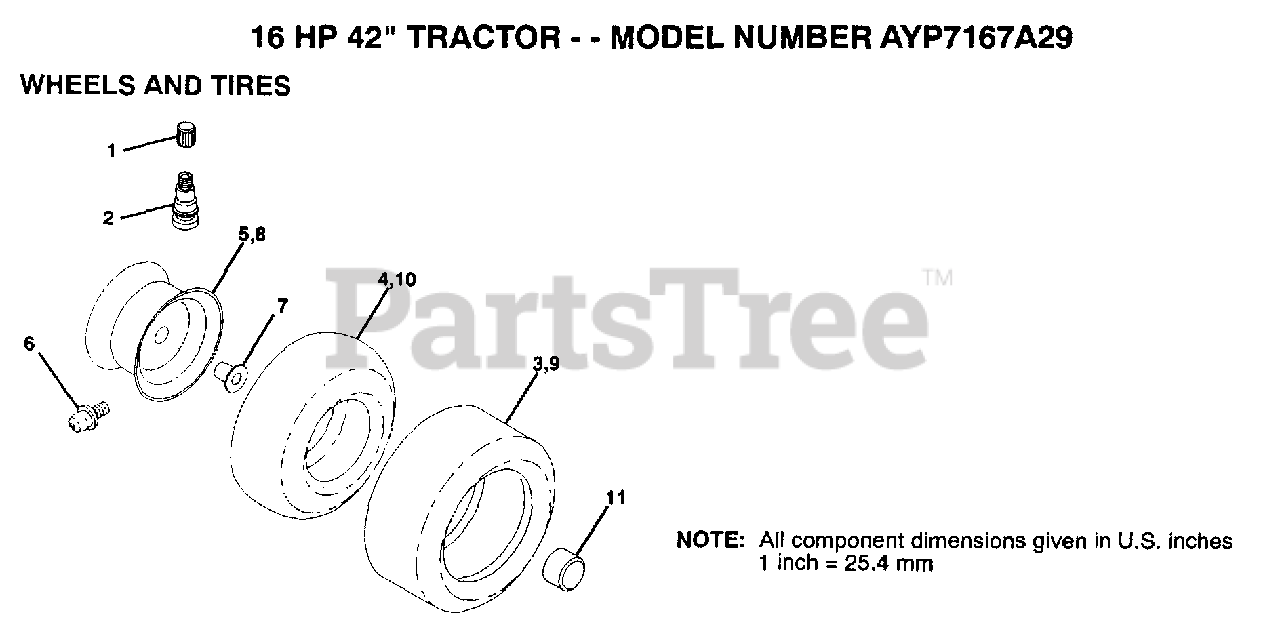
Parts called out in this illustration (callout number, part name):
1	VALVE CAP
2	VALVE STEM LT
4	TUBE.5.3/4.5/6
6	FITTING LT
7	"FLANGE, BEARING"
10	TUBE.18X9.5-8
11	HUB CAP
